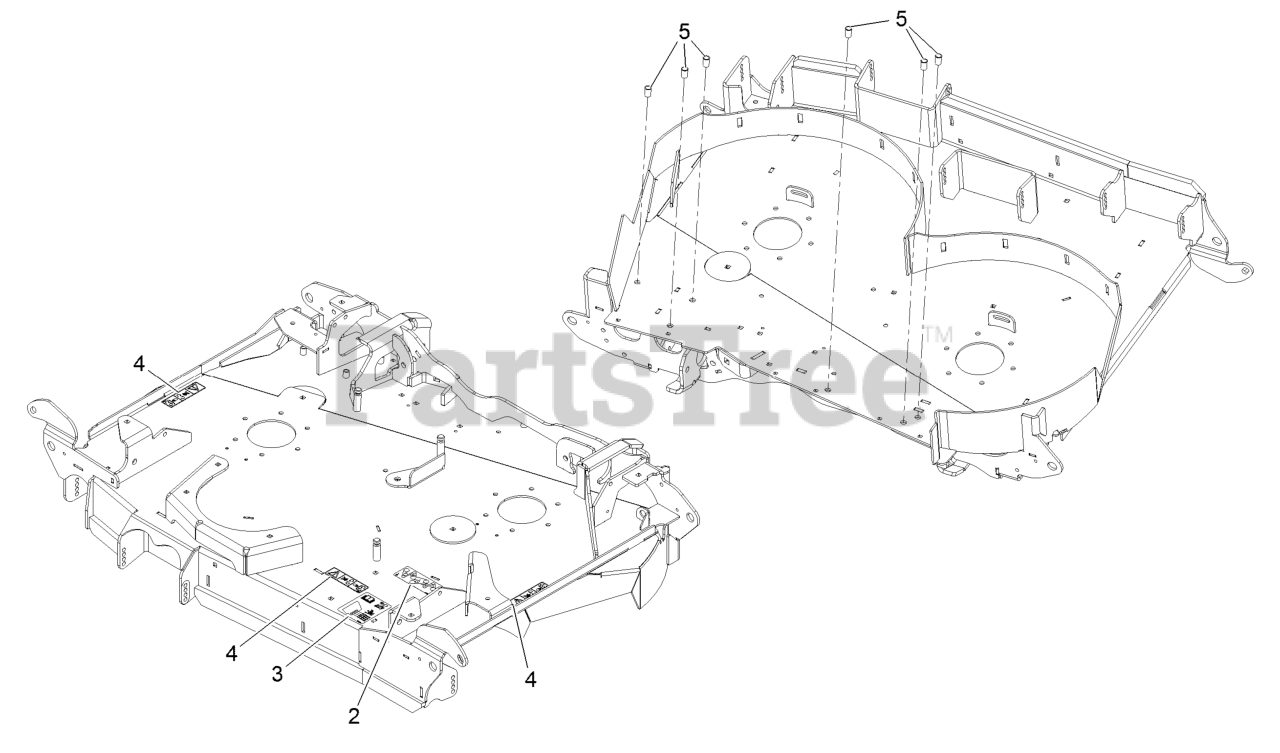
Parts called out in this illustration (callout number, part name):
2	Decal-Routing, Belt
3	Decal-Roller, Anti-Scalp
4	Decal-Cover, Missing
5	Insert-Nut
